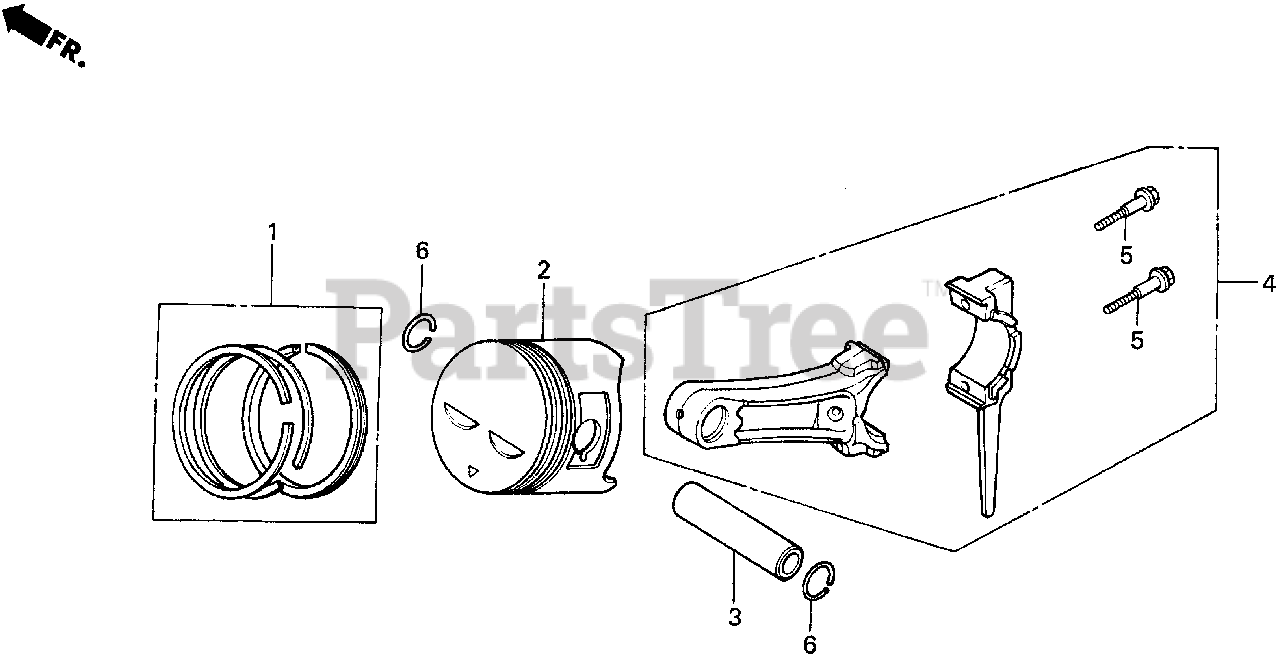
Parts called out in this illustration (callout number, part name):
1	RING SET, PISTON (STD)
1	RING SET, PISTON (OS 0.25) Use up to Engine SN 2623677.
1	RING SET, PISTON (OS 0.25) Use up to Engine SN 1281053.
1	RING SET, PISTON (OS 0.25)
1	RING SET, PISTON (OS 0.50) Use up to Engine SN 2623677.
1	RING SET, PISTON (OS 0.50) Use up to Engine SN 1281053.
1	RING SET, PISTON (OS 0.50)
1	RING SET, PISTON (0.75) Use up to Engine SN 2623677.
1	RING SET, PISTON (0.75) Use up to Engine SN 1281053.
1	RING SET, PISTON (0.75)
2	PISTON (STD)
2	PISTON (OS 0.25)
2	PISTON (OS 0.50)
2	PISTON (0.75)
3	PIN, PISTON
4	ROD ASSY., CONNECTING (STD)
4	ROD ASSY., CONNECTING
5	BOLT, CONNECTING ROD
6	CLIP, PISTON PIN (18MM)
